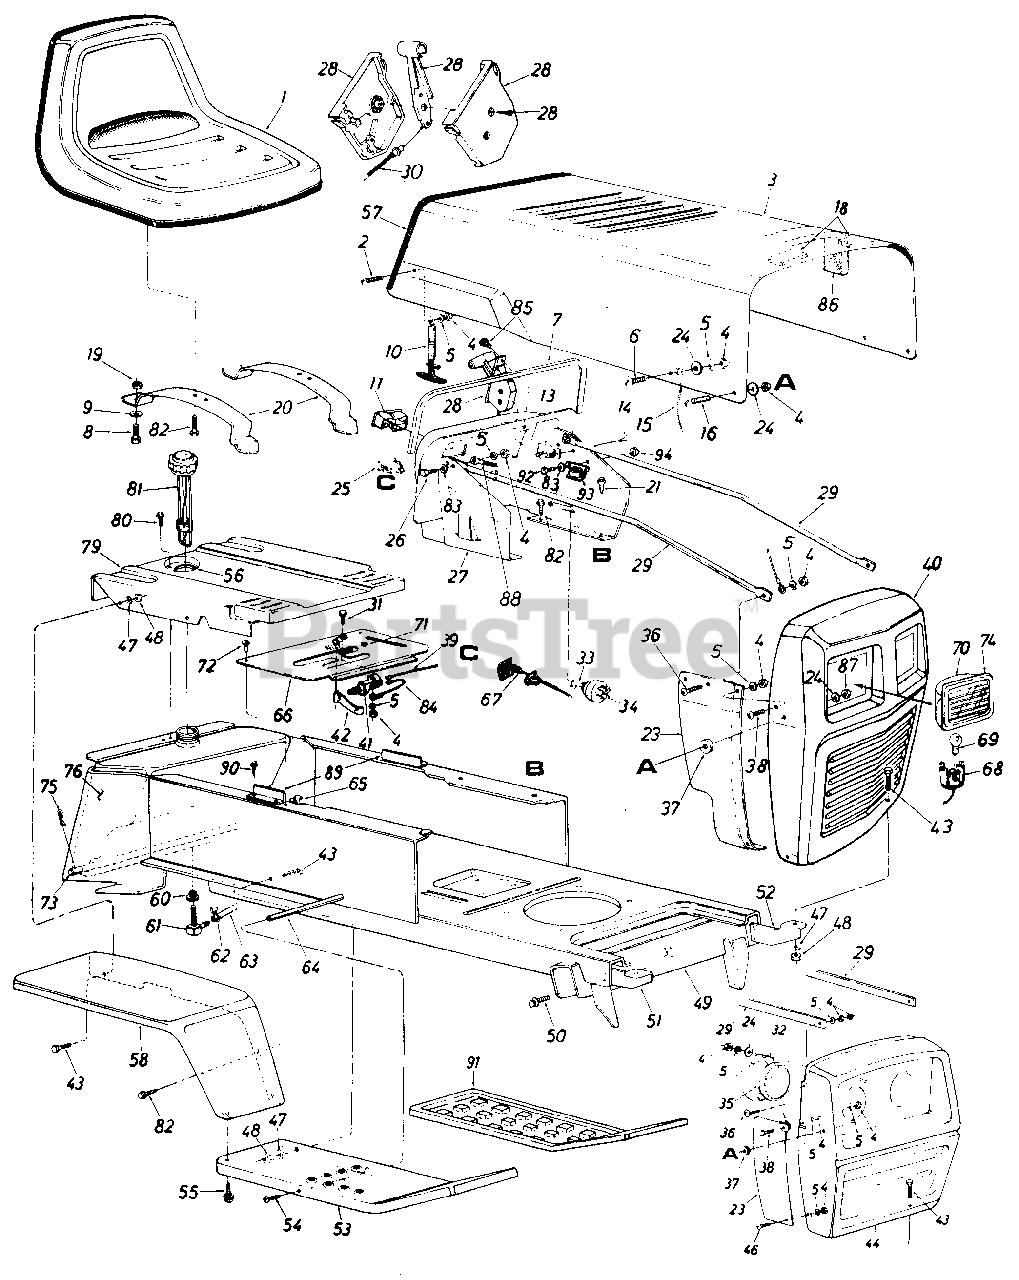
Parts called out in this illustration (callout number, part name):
1	Seat Assembly
2	Truss Mach. Scr. 1/4-20 x .50" Lg.
3	Hood
4	Hex Nut 1/4-20 Thd.
5	L-Wash. 1/4" I.D.
6	Truss Mach. Scr. 1/4-20 x .50" Lg.*
7	Vinyl Molding Strip-29"
8	Hex Nylon Scr. 1/2-13 x .75" Lg.
9	Fl-Wash. .50" I.D. x 1.00" O.D. x .090
10	Hood Latch Ass y.
11	Ammeter
13	Circuit Breaker 8 Amp.
14	Hex Tap Scr. #10 x .50"
15	Hood Stop
16	Truss Mach. Scr. 1/4-20 x .75" Lg.
18	PVC Foam Strip
19	Hex Nut 1/2-13 Thd.
23	Grille Side Panel-R.H.
24	Fl-Wash. 1/4" I.D.
25	Light Switch
26	Truss Hd. Scr. 1/4-20 x 1.00" Lg.
27	Dash Panel Ass'y.
28	Throttle Control Box Comp.
29	Grille Positioning Rod
30	Throttle Control Cable
31	Hex Bolt 1/4-20 x .50" Lg.
32	Head Lamp Retainer
33	Ignition Key
34	Ignition Switch
35	Head Lamp
36	Truss Machine Scr. 1/4-20 x .75" Lg.
37	Rubber Washer
38	Truss Mach. Scr. 1/4-20 x .50" Lg.
39	Reverse Lockout Wire Harness
42	Switch Actuator Spring Lever
43	Hex Bolt 5/16-18 x .75" Lg.
44	Grille (Painted)
46	Truss Mach. Scr. 1/4-20 x .50" Lg.
47	L-Wash. 5/16" I.D.
48	Hex Nut 5/16-18 Thd.
49	Lower Frame Ass'y.
50	Hex Thd. Rolling Scr. 5/16" x.75" Lg.
51	Grille Mount Brkt.-R.H.
52	Grille Mount Brkt.-L.H.
53	Running Board-R.H.
54	Truss Mach. Scr. 5/16-18 x .75" Lg.
55	Hex Thd. Rolling Scr. 5/16-24 x .75" Lg.
56	Grommet
57	Vinyl Moulding Strip-31"
58	Fender Ass'y.-R.H.
60	Bushing
61	90ø Nipple
62	Hose Clamp 3/8"
63	Gas Line 46" Lg.
64	Running Board Rod
65	Speed Nut #10-24
66	Transmission Cover Ass'y.
67	Choke Control Comp.
68	Socket
69	Lamp
70	Headlight Housing
71	Snap Bushing
72	Truss Hd. Scr. #10 x .50"
73	Hitch Rod
74	Lens
75	Internal Cotter Pin
76	Gas Tank
79	Seat Plate
80	Hex Thd. Rolling Scr. 5/16-24 x .75" Lg.
81	Gas Gauge
82	Hex Thd. Rolling Scr. 5/16-24 x .75" Lg.
83	External Wash. 1/4" I.D.
84	Electric Wire
85	Truss Mach. AB-Tap Scr. #10 x .50" Lg.
86	PVC Foam Strip
87	Hex L-Nut 1/4-20 Thd.
88	Ground Wire
89	Seat Spring Guide
90	Hex AB-Tap Scr. 1/4 x .625" Lg.
91	Foot Pad
92	Hex Bolt 1/4-20 x .5" Lg.
93	Solenoid
94	Hex Sems Nut 1/4-20 Thd.
